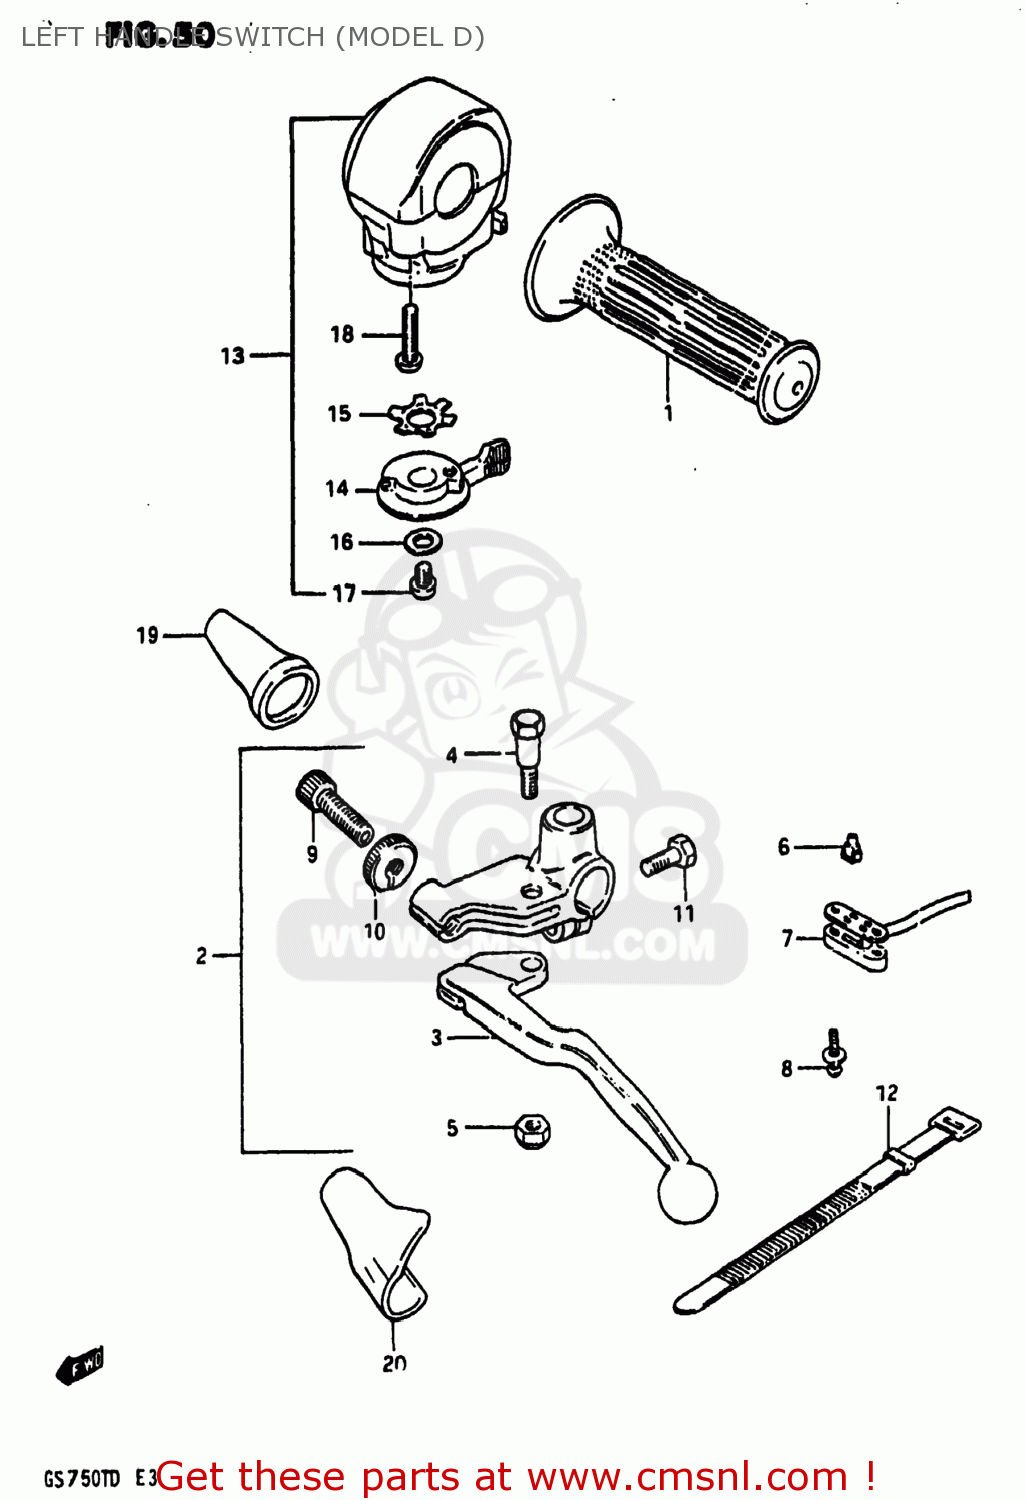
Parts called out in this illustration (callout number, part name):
1	GRIP,LEFT
2	LEVER ASSEMBLY
3	LEVER,CLUTCH
4	BOLT,LEVER
5	NUT 6MM
6	CONTACT,SWITCH
7	COVER,FR BK TERMINAL BASE
8	SCREW
9	ADJUSTER,CABLE
10	NUT,CABLE ADJUSTER
11	BOLT,CLUTCH LEVER HOLDER
12	CLAMP(L:120)
13	SWITCH ASSEMBLY,HANDLE,LEFT
14	LEVER,STARTER
15	WASHER
16	WASHER 6MM
17	SCREW
18	SCREW
19	BOOT,CLUTCH CABLE
20	COVER,CLUTCH LEVER
